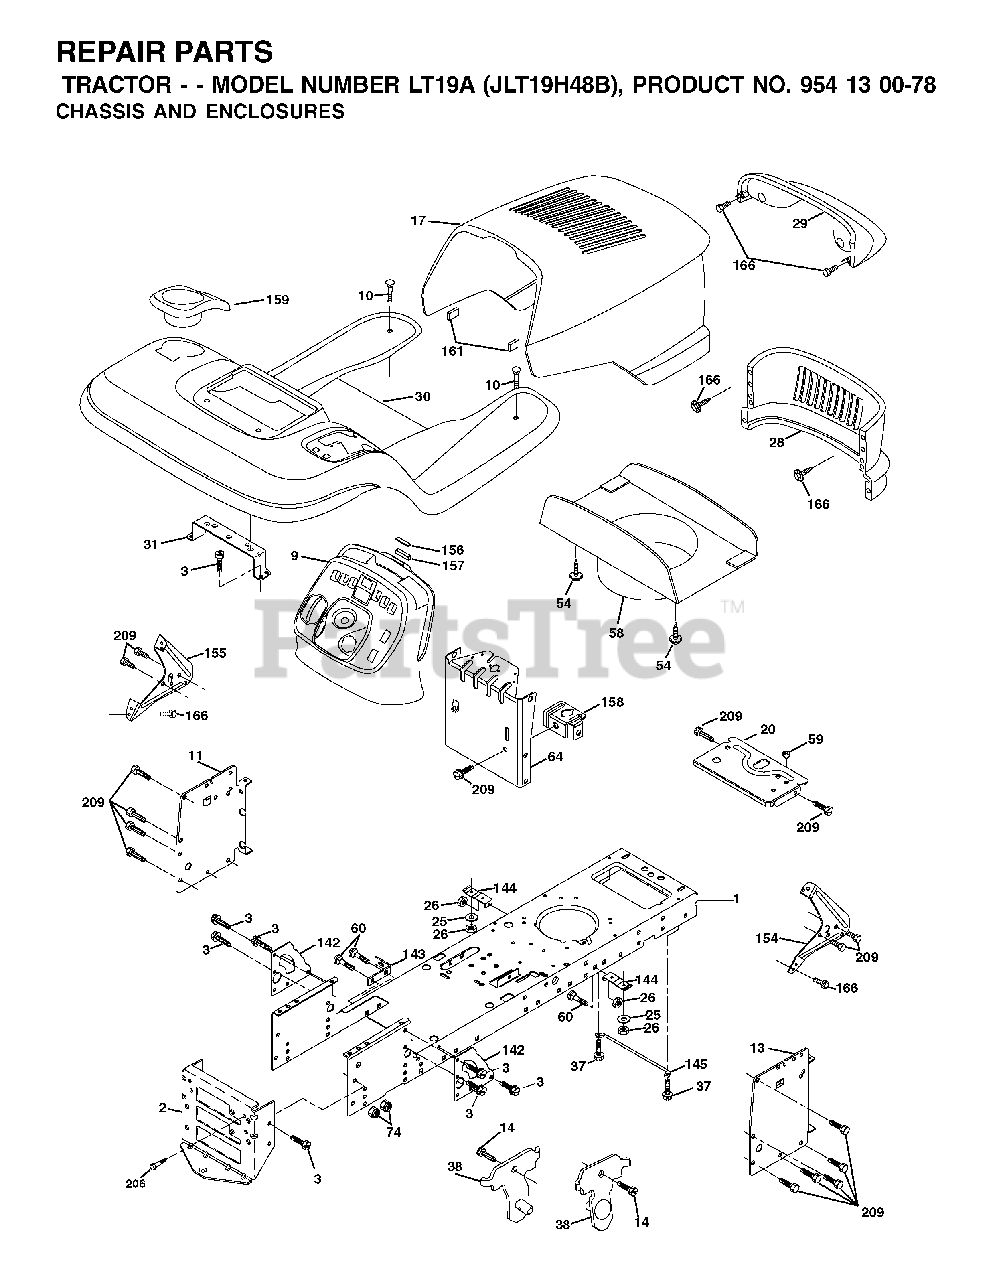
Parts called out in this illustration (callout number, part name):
1	CHASSIS STAMPING
2	DRAWBAR, 12GA
3	SCREW 3/8-16X3/4
10	BOLT D
13	PANEL DASH RH
25	WASHER
26	NUT
38	BRACKET.ASM.PIVOT.MOWER.REAR
58	DUCT HOOD
59	BUSHING 1.375 OD
64	DASH LOWER
74	LOCKNUT
142	PLATE REINFORCEMENT
143	BRACKET, SWAY BAR
144	BRKT, FOOT REST
145	ROD PIVOT CHASSIS/HOOD
161	EXTRUSION BUMPER
166	SCREW
206	SHOULDER BOLT 5/16-18TT
209	SCREW, 3/8-16X3/4
